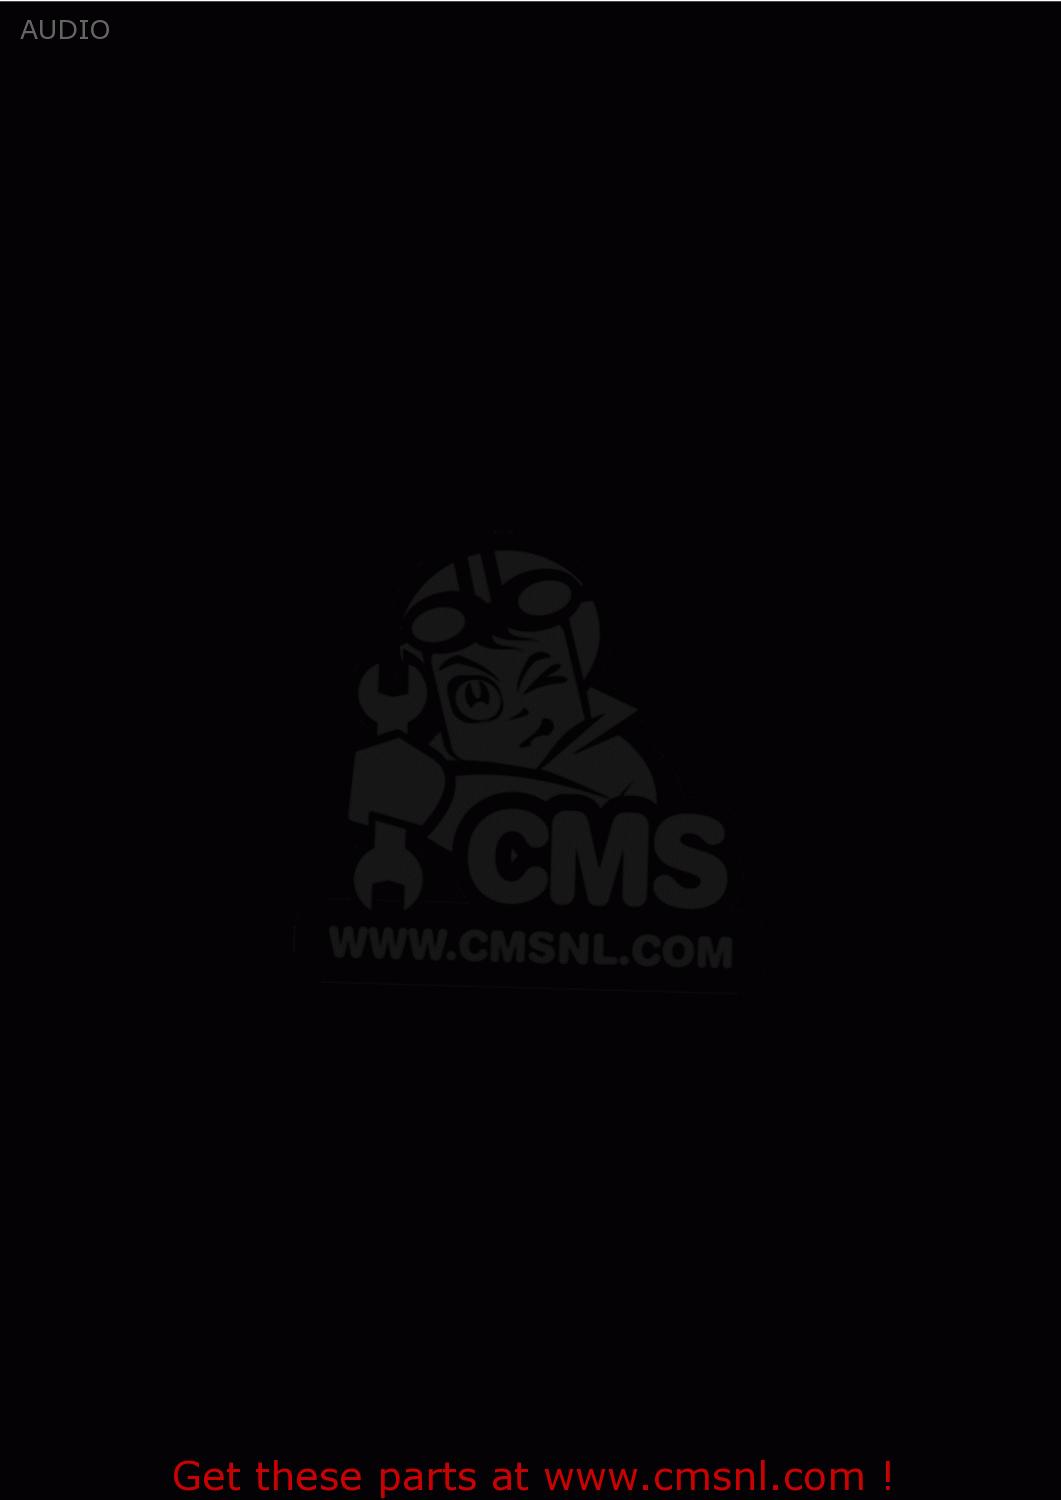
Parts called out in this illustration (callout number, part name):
1	TUNER ASSEMBLY
1A	KNOB,TUNER
1B	KNOB,TUNER
1C	KNOB,TUNER
2	CASE ASSEMBLY,TUNER
3	BOLT,M6X1X20
4	WASHER,LOCK
5	SPEAKER
5A	SPEAKER
5B	SPEAKER ASSEMBLY,REAR,LEFT
6	SCREW
7	WASHER
8	WIRE,SPEAKER LEAD
9	COVER,SPEAKER
10	CLAMP
11	GRILLE,SPEAKER,RIGHT
12	GRILE,SPEAKER,L
13	CUSHION
14	SWITCH,RADIO CHANNEL SELECT
15	SCREW
16	WIRE,RADIO CHANNEL SELECTOR
17	INDICATOR ASSEMBLY,TUNER C
18	BULB 14V
19	WASHER (4X16X1.2)
20	SPACER
21	SCREW
22	SCREW
23	CONDENSER ASSEMBLY,REGULATOR
24	SPACER (6.5X10.5X13.5)
25	FILTER ASSEMBLY,FAN MOTOR
26	27
27	SCREW
29	WIRE,AUDIO POWER SOURCE
30	ANTENNA ASSEMBLY,TUNER
31	CONTROLLER ASSEMBLY,TUNER
31A	CONTROLLER ASSEMBLY,TUNER
32	WIRE,CHANNEL SELECT SWITCH
32A	WIRE,SPEAKER LEAD
33	SCREW
34	SWITCH
35	CLAMP(L:125)
